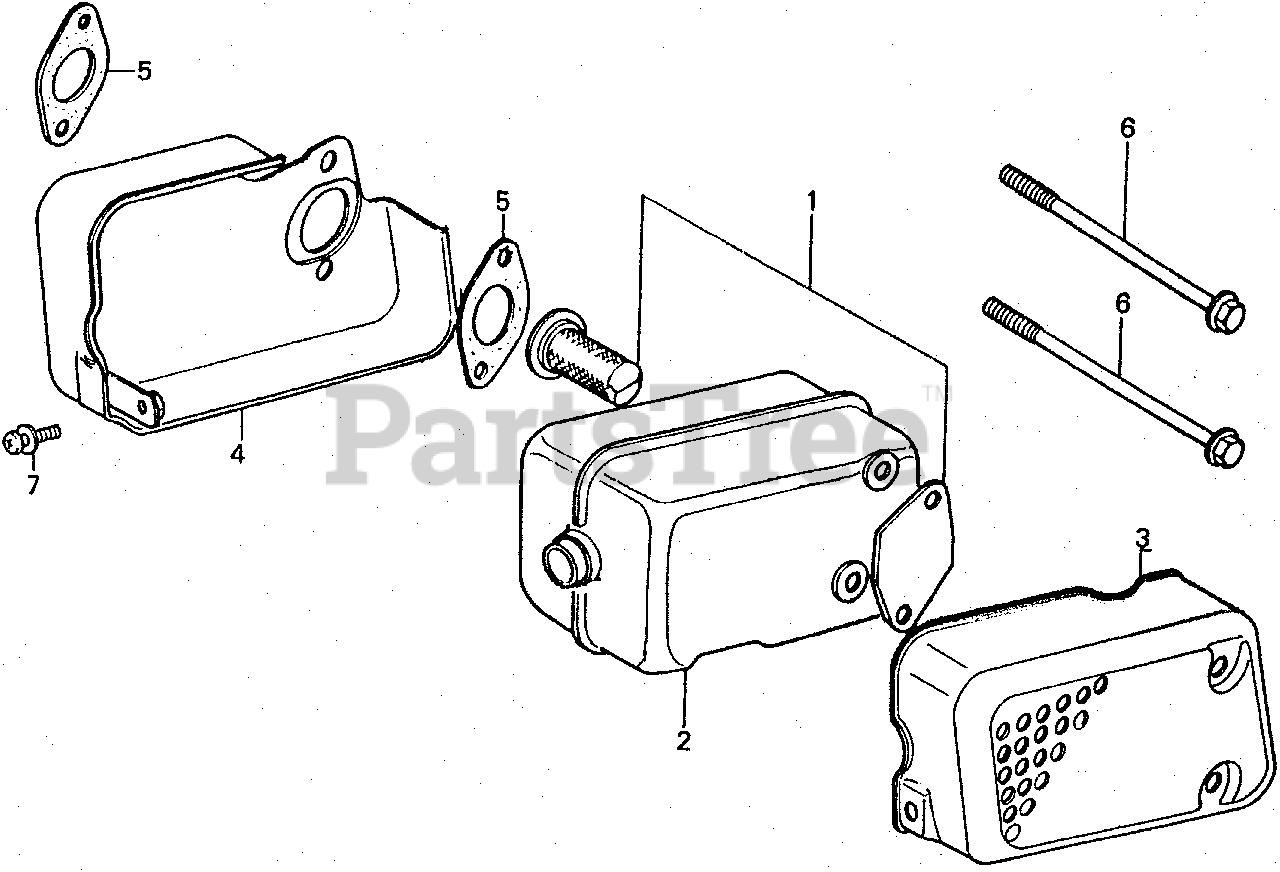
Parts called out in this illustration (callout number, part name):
1	ARRESTER KIT, SPARK (NOT AVAILABLE)
2	MUFFLER (NOT AVAILABLE)
3	PROTECTOR, MUFFLER (NOT AVAILABLE)
4	SEPARATOR, MUFFLER (NOT AVAILABLE)
5	GASKET, MUFFLER
6	BOLT, FLANGE (8X104) (NOT AVAILABLE)
7	SCREW-WASHER (5X10)
